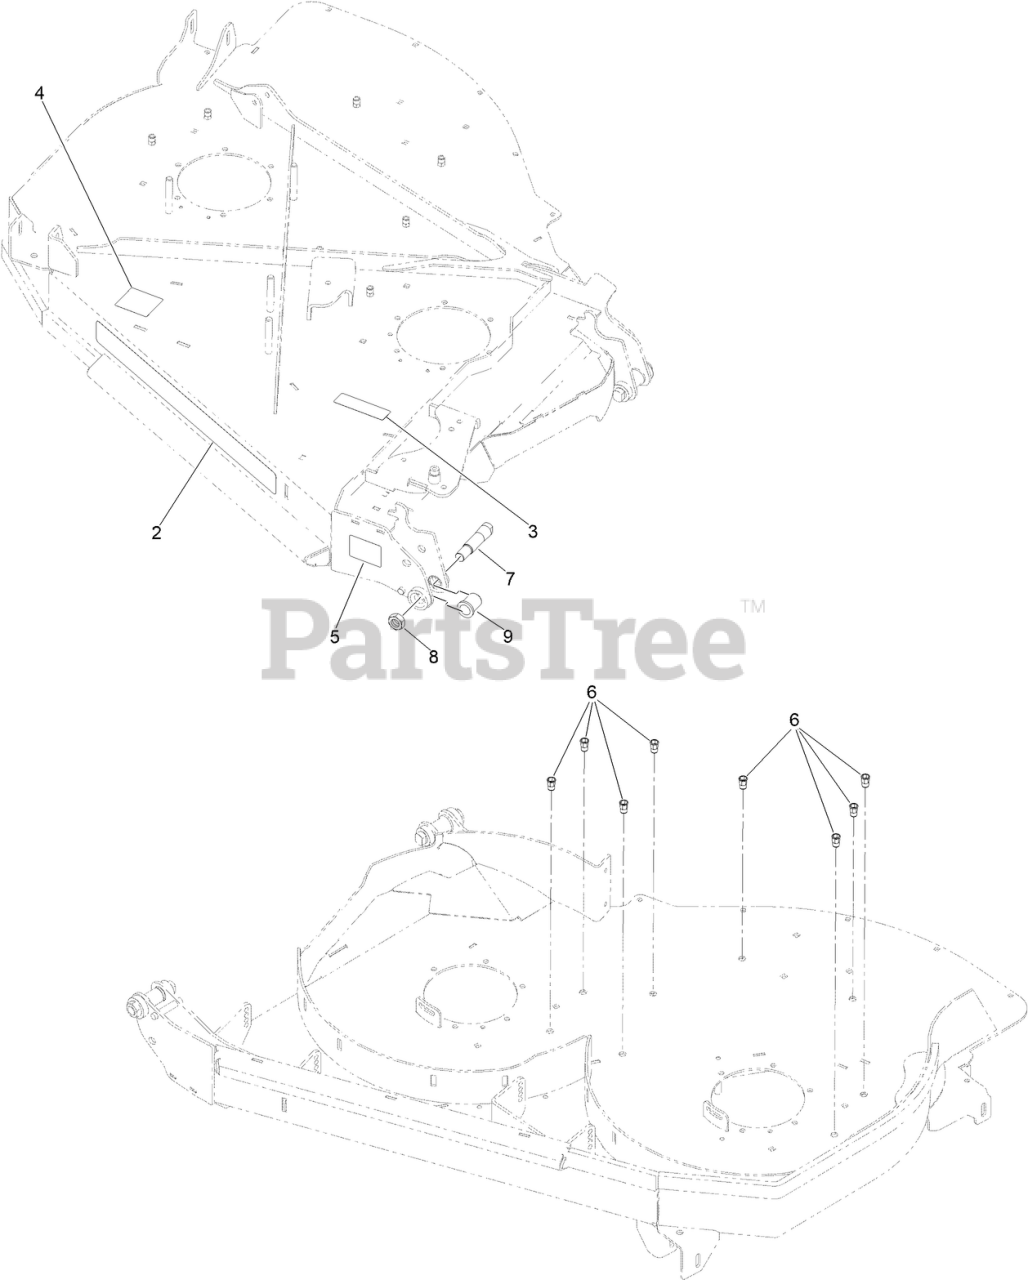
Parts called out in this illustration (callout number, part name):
2	DECAL-144 INCH
3	DECAL-COVER, MISSING
4	DECAL-DANGER, THROWN OBJECT
5	DECAL-WARNING, PINCH POINT
6	NUT-CLINCH,HEX
7	BOLT-PIVOT PIN
8	NUT-LUG
9	BUSHING-FLANGED
